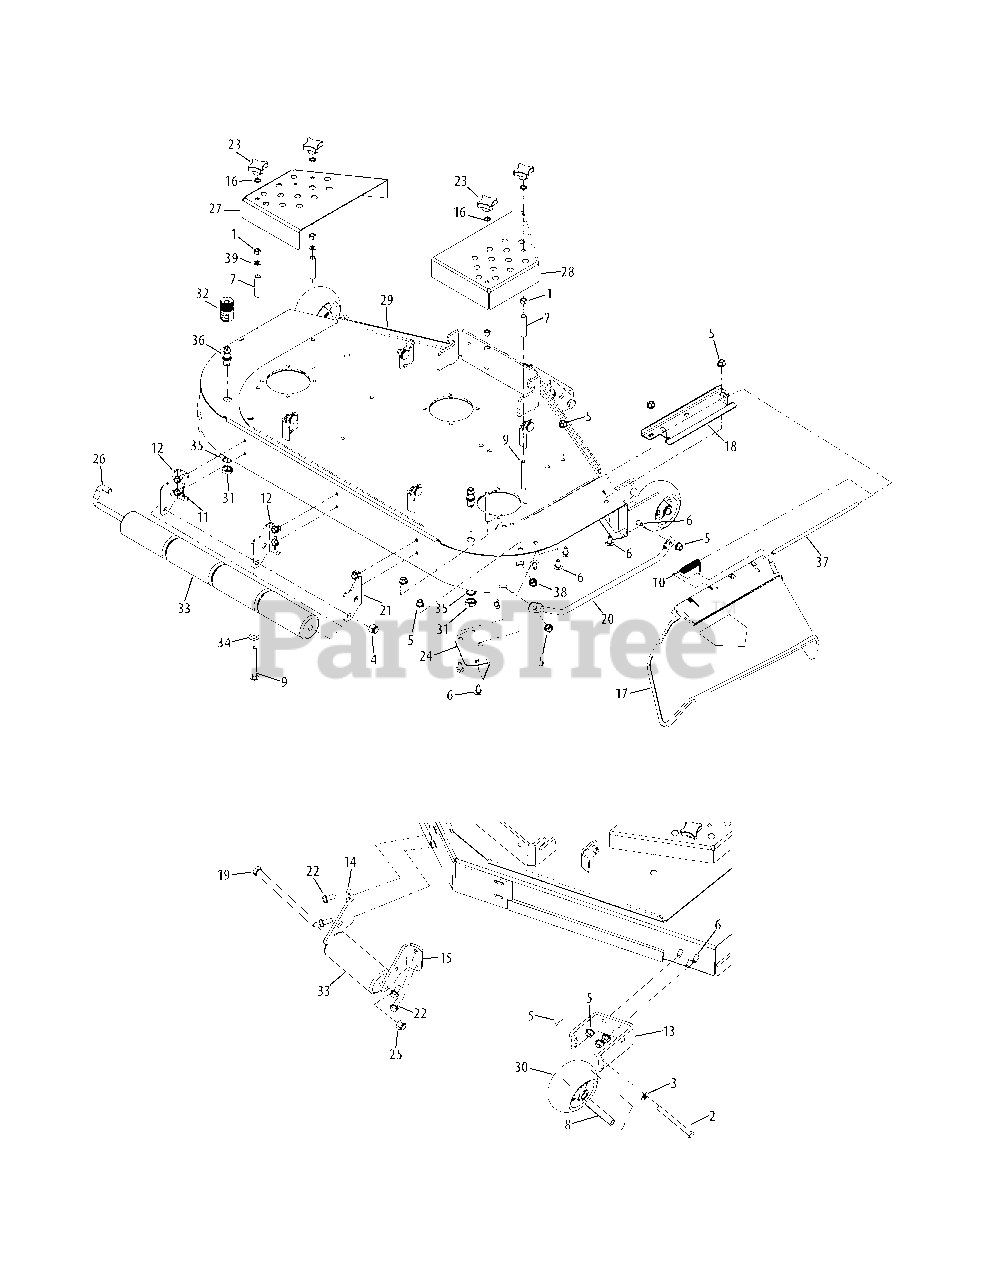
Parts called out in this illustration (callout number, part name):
1	Nut, 3/8-16
2	Hex Screw, 3/8-16 x 4.00
3	Washer, .406 x .813 x .063
4	Hex Lock Nut, 1/2-13
5	Flange Counterlock Nut, 3/8-16
6	Carriage Bolt, 3/8-16 x .75
7	Spacer, .400 x .560 x 2.45
8	Spacer, .390 x .620 x 3.04
9	Carriage Bolt, 3/8-16 x 3.50
10	Torsion Spring, .639 x 2.16 x .12
11	Flange Screw, 3/8-16 x .500
12	Roller Mount Bracket
13	Anit-Scalp Front Mount Bracket
14	LH Front Roller Mount Bracket
15	RH Front Roller Mount Bracket
16	Washer, .398 x .694 x .032
17	Chute Deflector
18	Chute Deflector Bracket
19	Hex Screw, 1/2-20 x 7.50
20	Finger Guard
21	RH Roller Mt. Brkt.
22	Flange Screw, 3/8-16 x .875
23	Plastic Knob, 3/8-16
24	Micro Chute Baffle
25	Nut, 1/2-20
26	J-Hook
27	LH Belt Cover
28	RH Belt Cover
29	Deck Assembly
31	Hex Nut
32	Water Nozzle Adapter
33	Front Roller
34	Flat Washer, .510 x 1.00 x .060
35	Lock Washer, 17 x 23.8 x 1.95
36	Water Deck Nozzle
37	Chute Deflector Rod
38	Nut, Flange Lock, 3/8-16, Grf,
39	Washer, Lock, 3/8 , Regular Duty
